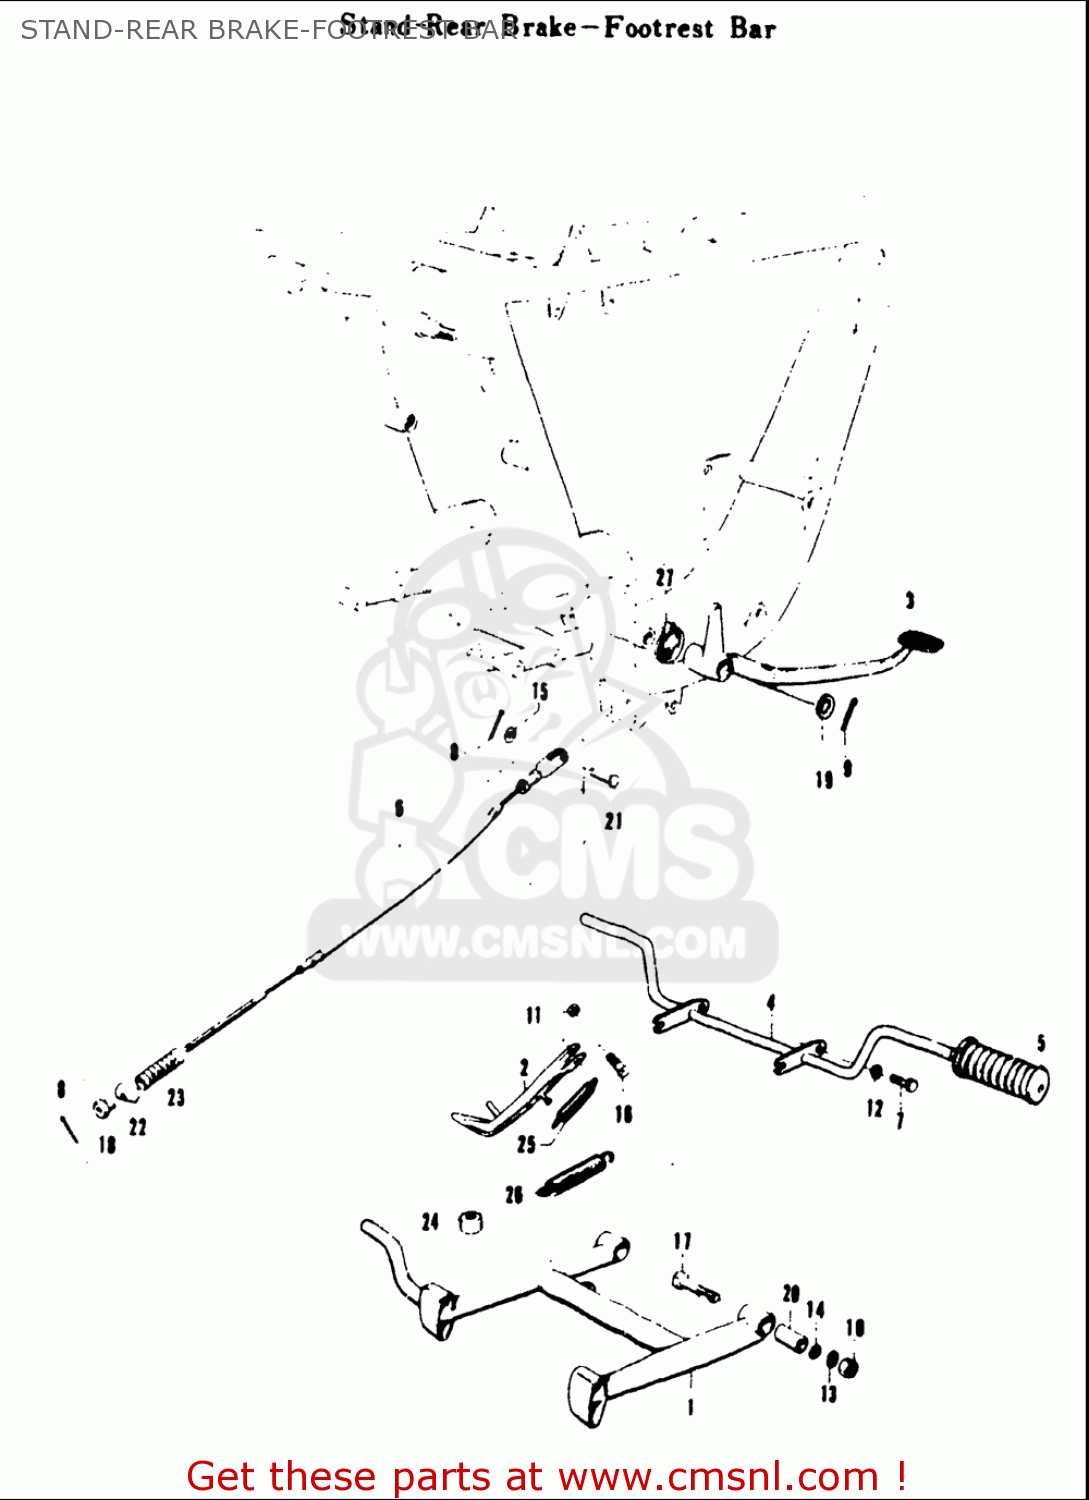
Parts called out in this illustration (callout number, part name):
2	STAND,PROP
5	RUBBER,FR FOOTREST
6	CABLE ASSY,RR BRAKE
7	BOLT
9	PIN
10	NUT
11	NUT
12	WASHER,LOCK
13	WASHER,LOCK
14	WASHER
15	WASHER
16	BOLT(10X27)
17	CENTER STAND BOLT
18	NUT
20	SPACER(10.5X16X30)
21	PIN(L:17.5)
22	PIN(13X18)
23	SEAL,DUST
24	CUSHION
25	SPRING
26	SPRING
27	SPRING
